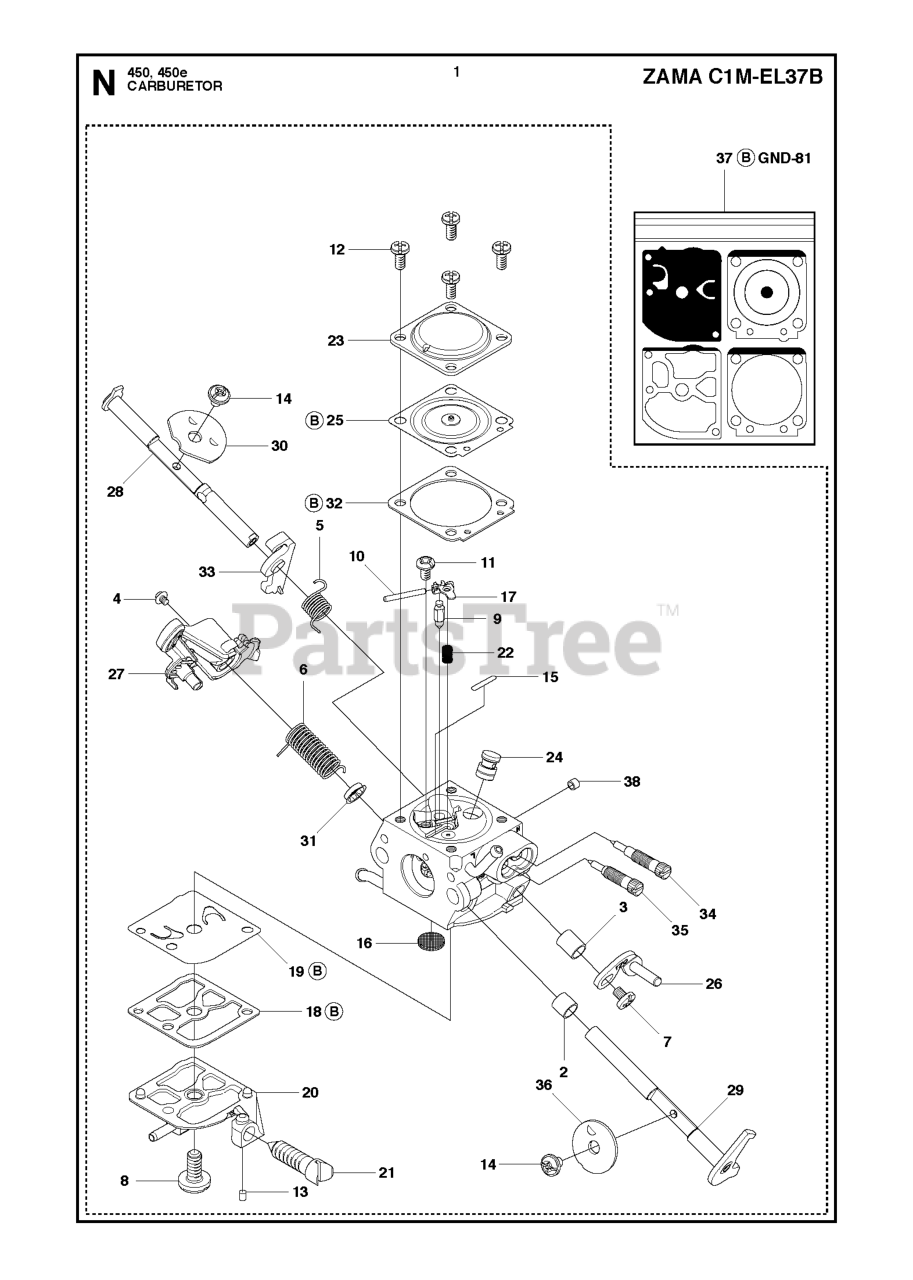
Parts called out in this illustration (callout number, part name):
1	CARBURETOR
9	INLET NEEDLE
10	PIN RETAINING SCREW
19	PUMP DIAPHRAGM
27	THROTTLE LEVER
28	SHAFT ASSY
29	SHAFT ASSY
30	CHOKE VALVE
37	GASKET KIT
